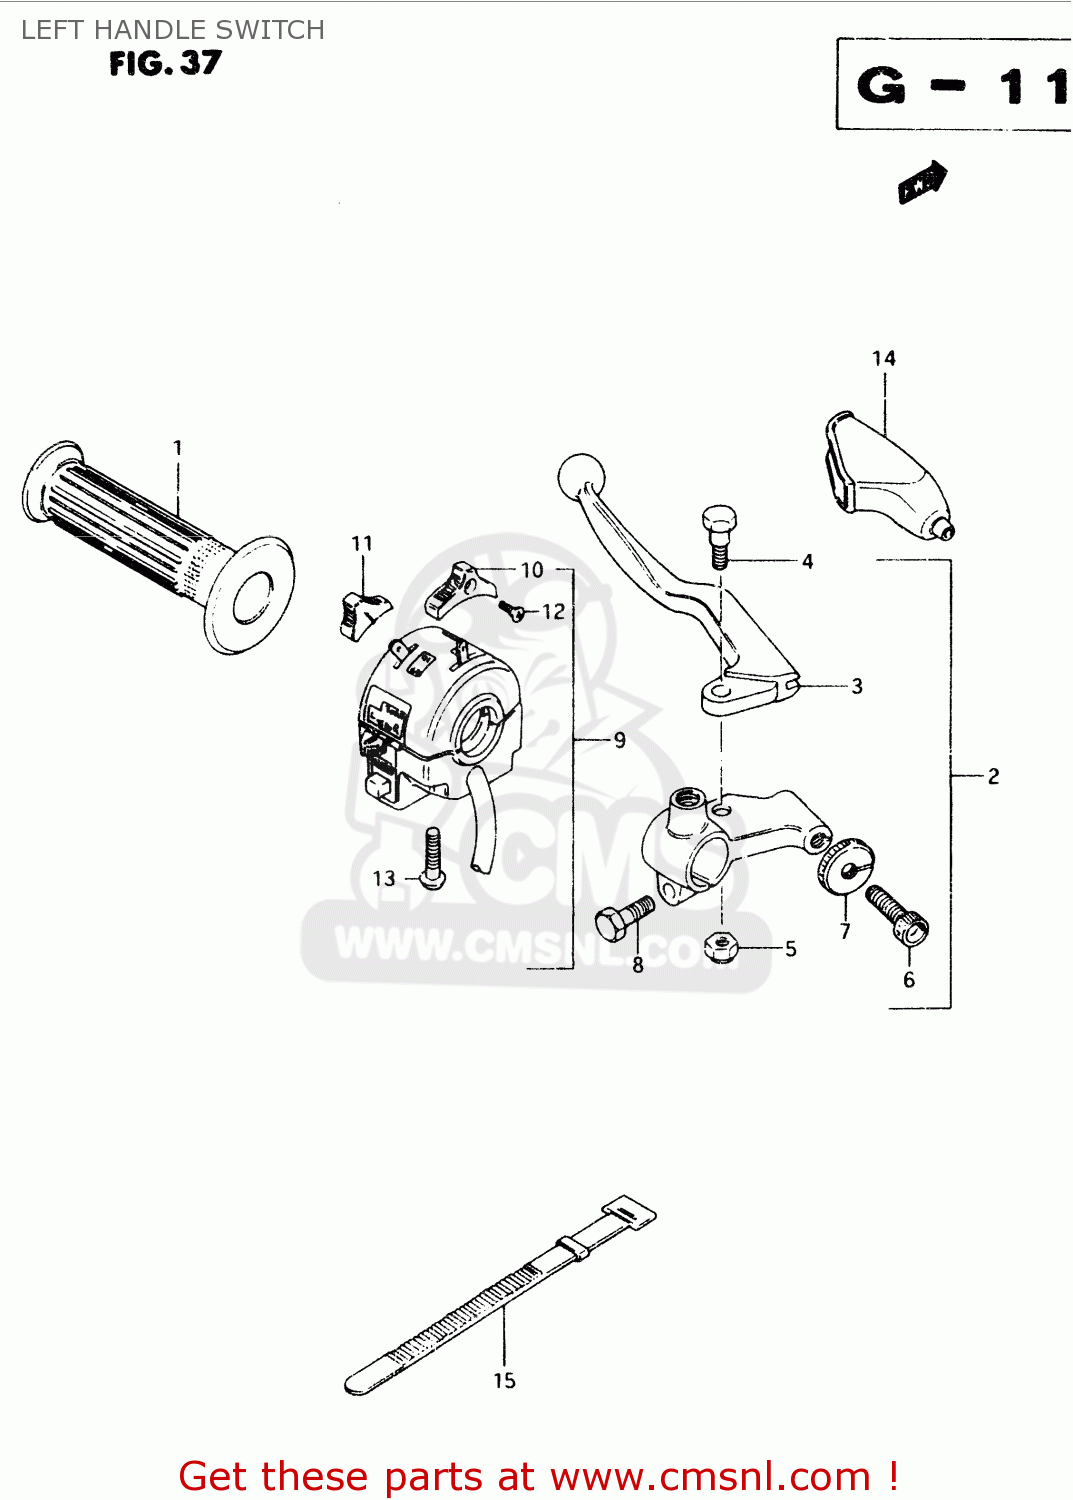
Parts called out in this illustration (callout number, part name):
1	GRIP,LEFT
2	LEVER ASSY,CLUTCH
3	LEVER,CLUTCH
4	BOLT,LEVER PIVOT
5	NUT 6MM
6	ADJUSTER,CABLE
7	NUT,CABLE ADJUSTER
8	BOLT
9	SWITCH ASSY,HANDLE,L
10	KNOB,LIGHTING SWITCH
11	KNOB,DIMMER SWITCH
12	SCREW
13	SCREW
14	COVER,CLUTCH LEVER
15	CLAMP(L:120)
